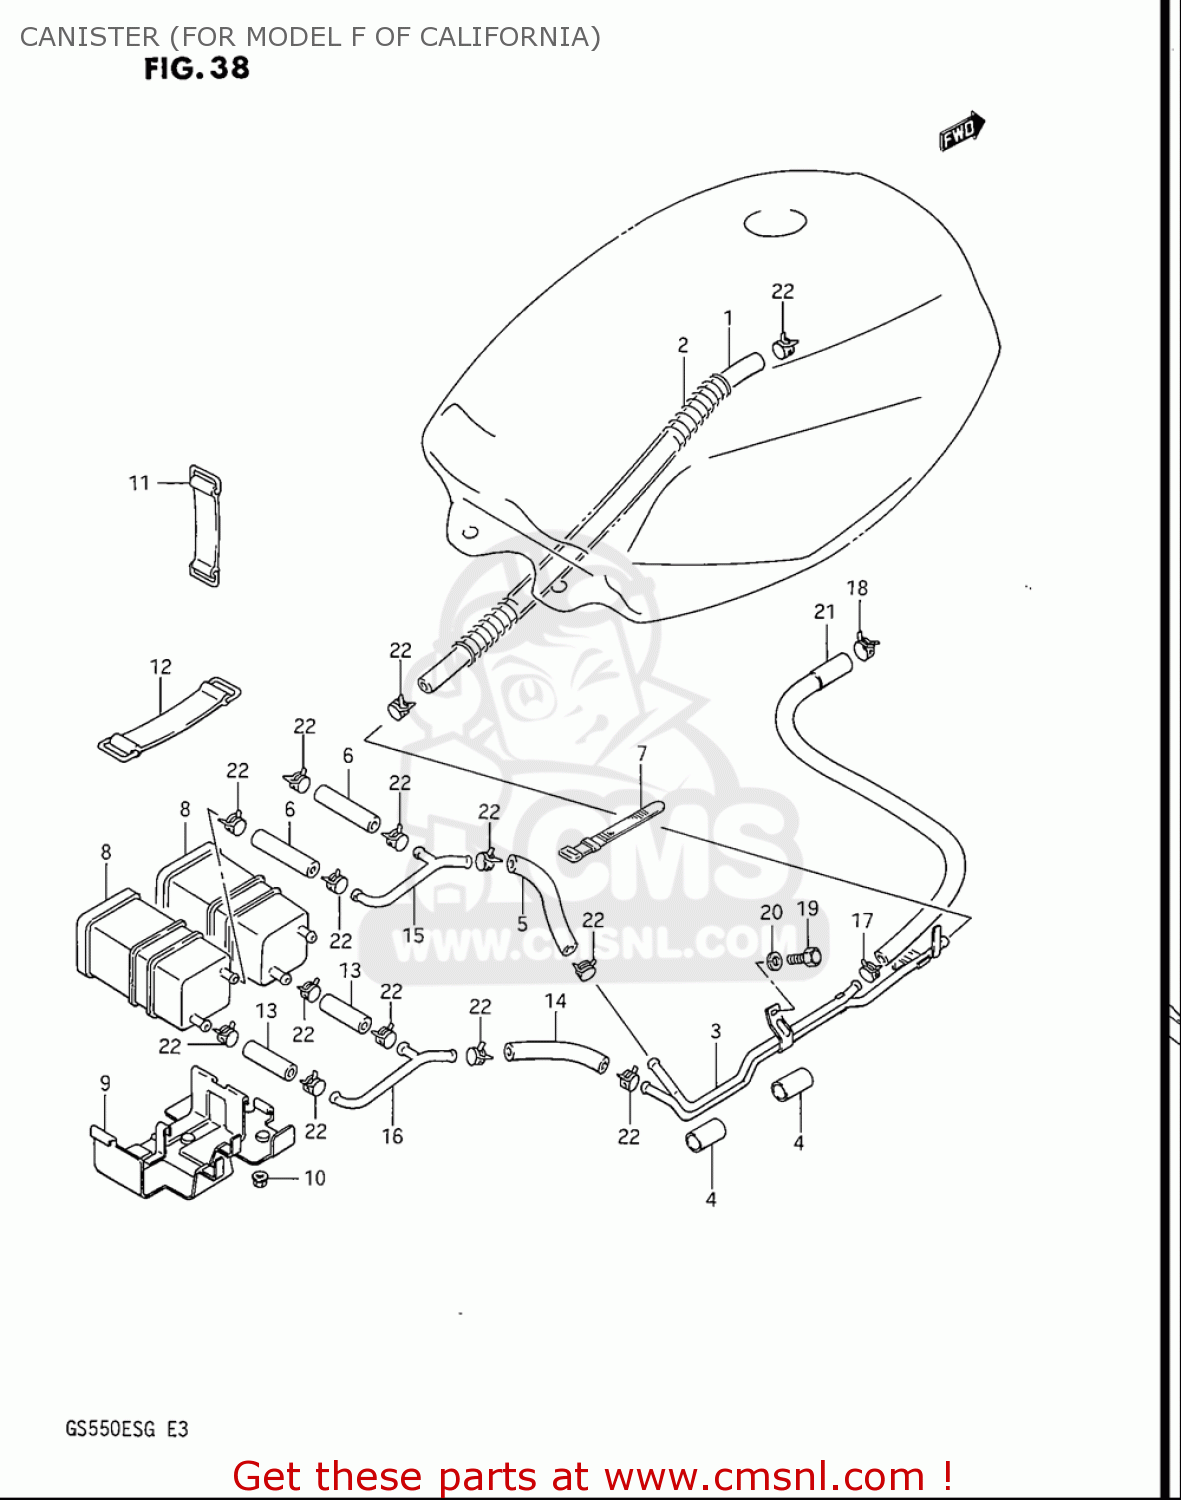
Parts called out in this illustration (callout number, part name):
1	HOSE(5.4X11.4X2000)
2	SPRING
5	HOSE(5.4X11.4X2000)
7	CLAMP(L:187)
8	CANISTER ASSY,CHARCOAL
10	NUT
11	BAND
12	BAND
13	HOSE(5.4X11.4X600)
14	HOSE(5.4X11.4X600)
17	CLIP
18	CLAMP
19	BOLT
20	WASHER
21	HOSE(5.4X11.4X1000)
22	CLIP
